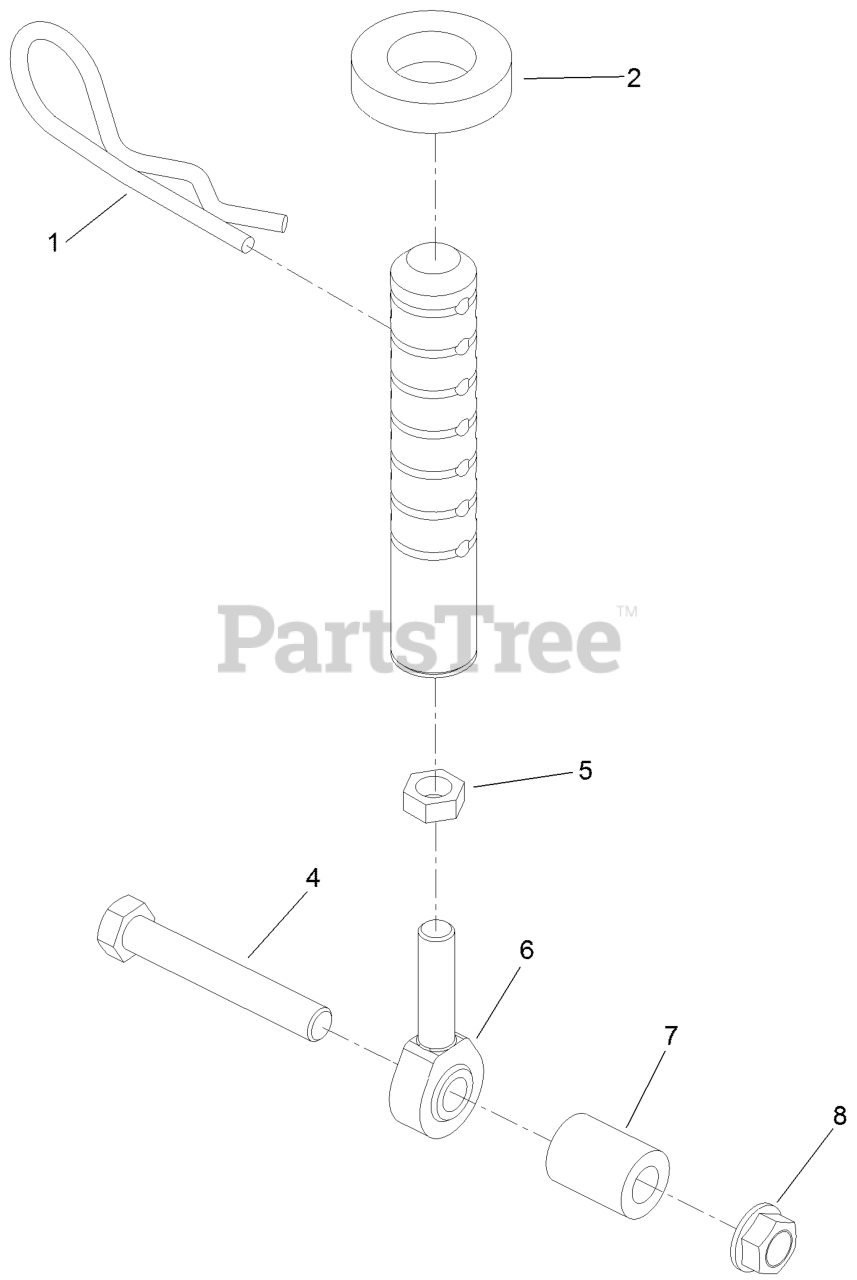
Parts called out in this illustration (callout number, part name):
1	PIN-CUT HEIGHT
2	SPACER-DECK SUPPORT
4	SCREW-HH
5	NUT-HJ
6	BALLJOINT
7	TUBE-INTERLOCK
8	NUT-HHF, WHIZ
